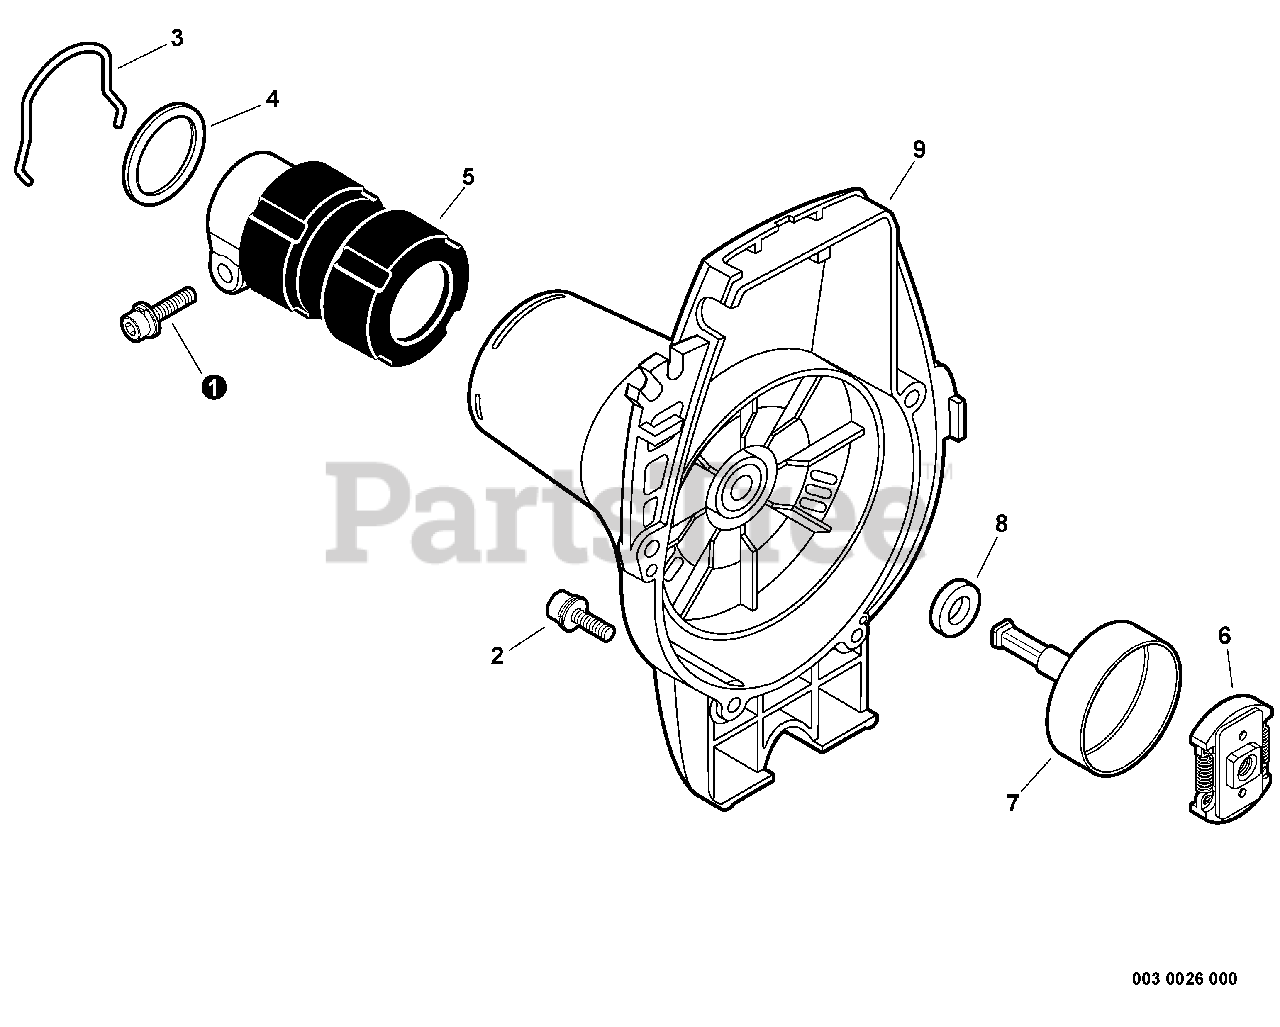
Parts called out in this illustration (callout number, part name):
1	SCREW - 5X28
2	SCREW - 4X16
5	CLAMP, MAIN PIPE
6	CLUTCH ASSY
7	DRUM, CLUTCH
9	FAN CASE ASSY
